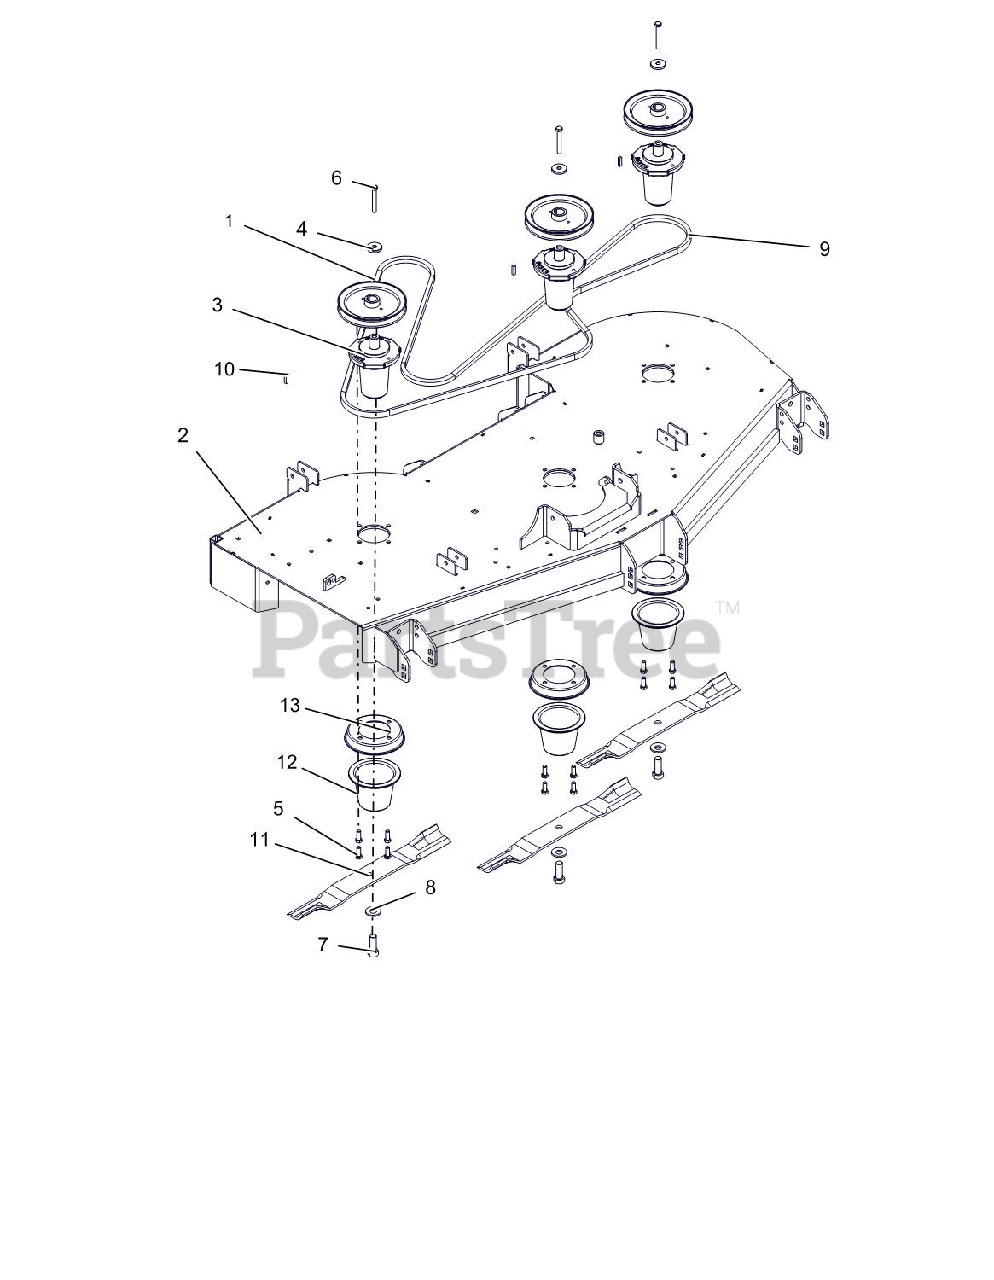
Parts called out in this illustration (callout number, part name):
1	PULLEY, 1.00 ID X 6.75 OD
2	KIT, 60" MOWER DECK W DECALS
3	ASM, MAINT FREE SPINDLE
4	RETAINER, SHEAVE
5	BLT-HEX .38-16X1.0 GR8 YZ EP30
6	BLT-HEX .38-16X2.75 GR8 YWZC
7	BLT-HEX .62-18X1.75 GR8 YWZC
8	WSHR-BLVL .669X1.535X.138
9	BELT, B-SECTION EPDM RAW EDGE
10	KEY, SQ .25X.25X1.00 RC 40-50
11	BLADE, MOWER (20.50")
12	GUARD, SPINDLE LOWER
13	GUARD, SPINDLE TOP
